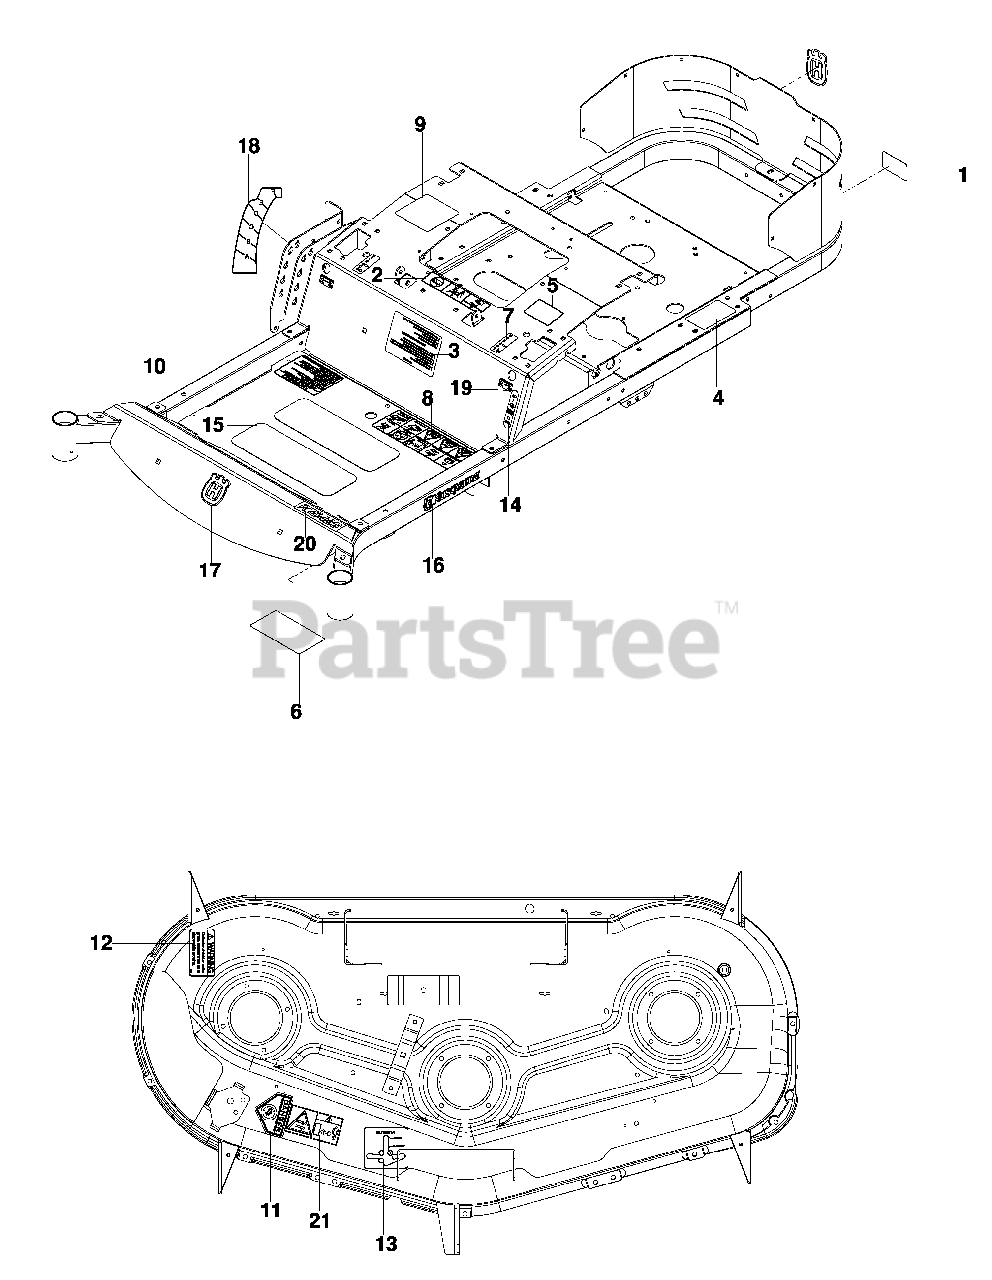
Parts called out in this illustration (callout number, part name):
1	DECAL, PROP 65
2	DECAL, BATTERY WARNING
3	DECAL, START
4	DECAL, DO NOT TOW
5	DECAL, EXIT MOWER
6	DECAL, SERVICE
7	DECAL, MOTION CONTROL
8	DECAL, SAFETY WARN
9	DECAL, RESPONSIBILITY
10	DECAL, WARNING
11	DECAL, CPSC
12	DECAL, WARNING
13	DECAL, BELT ROUTING
14	DECAL, PARK BRAKE
15	ABRASIVE PAD
16	DECAL, HUSQVARNA
17	DECAL, CROWN H
18	DECAL, HEIGHT
19	DECAL, FST
20	DECAL, EZ4824
21	DECAL, SEVERING
